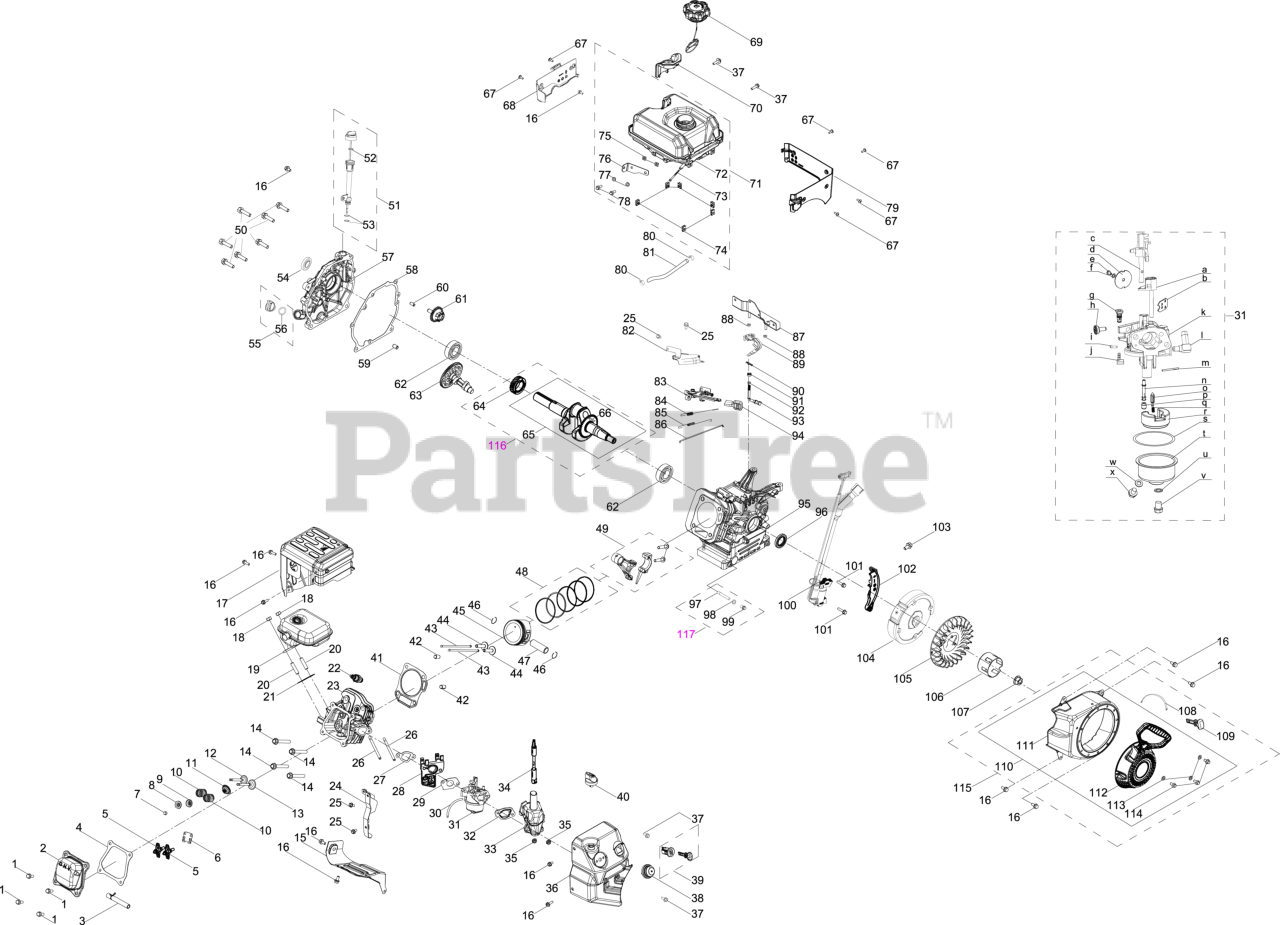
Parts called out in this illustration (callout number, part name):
1	BOLT M6 x 16
2	VALVE COVER
3	BREATHER HOSE
4	VALVE COVER GASKET
5	ROCKER ARM KIT
6	ROCKER ARM BASE
7	EXHAUST VALVE ADJUSTER
8	EXHAUST VALVE SPRING RETAINER
9	INTAKE VALVE SPRING RETAINER
10	VALVE SPRING
11	INTAKE VALVE SEAL
12	EXHAUST VALVE
13	INTAKE VALVE
14	BOLT M8-1.25 x 55 GR10.9
15	AIR SHIELD
16	BOLT M6-1 x 12 GR8.8
17	MUFFLER GUARD
20	STUD M8 x 36
21	MUFFLER GASKET
22	SPARK PLUG (F6RTC/RN11YC/BPR6ES)
23	CYLINDER HEAD
24	SNOW GUARD
25	BOLT M6-1 x 12 GR8.8
26	STUD M6 x 90
27	CARBURETOR INSULATOR GASKET
29	CARBURETOR GASKET
30	PRIMER HOSE
31	CARBURETOR ASSEMBLY
32	CARBURETOR GASKET PLATE
33	HEATER BOX
34	CHOKE LEVER
36	CONTROL PANEL
37	BOLT M6-1 x 18 GR8.8
39	ENGINE KEY SWITCH ASSEMBLY
40	CHOKE LEVER
41	CYLINDER HEAD GASKET
43	PUSH ROD
46	PISTON PIN SNAP RING
47	PISTON PIN
48	PISTON RING SET
49	CONNECTING ROD
50	BOLT M8-1.25 x 32 GR5.8
51	DIPSTICK ASSEMBLY
52	DIPSTICK O-RING
53	OIL FILL TUBE O-RING
56	O-RING 15.8 x 2.5
57	CRANKCASE COVER
58	CRANKCASE GASKET
59	DOWEL PIN 9 X 14
60	DOWEL PIN 9 X 14
61	GOVERNOR GEAR
64	DRIVE TIMING GEAR
65	CRANKSHAFT
66	WOODRUFF KEY
67	BOLT: M5 x 14
68	FUEL TANK SHROUD (RH)
70	DECORATIVE COVER
72	FUEL TANK
73	FUEL FILTER
74	FUEL TANK MOUNT THREADED TAB
76	FUEL TANK MOUNT TAB
77	WASHER 6.5 x 1.5 x 12
78	BOLT M6 x 20
79	FUEL TANK SHROUD (LH)
80	HOSE CLAMP
81	FUEL HOSE 6.3 x 12.5 x 162
82	GOVERNOR SHIELD
83	GOVERNOR GEAR BRACKET ASSEMBLY
84	GOVERNOR SPRING
85	THROTTLE SPRING
86	THROTTLE LINKAGE
87	FUEL TANK BRACKET
89	GOVERNOR LEVER
90	COTTER PIN
91	GOVERNOR SEAL
93	GOVERNOR SHAFT
94	THROTTLE CONTROL KNOB
96	OIL SEAL
97	OIL DRAIN PIPE
98	WASHER
99	OIL DRAIN PLUG
100	IGNITION MODULE
101	BOLT M6-1 x 25 GR8.8
102	LOWER SHIELD
103	SCREW M6-1 x 20 CL5.8
105	COOLING FAN
106	STARTER CUP
107	FLYWHEEL NUT
108	CABLE TIE - 3 x 150
109	IGNITION KEY
110	RECOIL STARTER
111	BLOWER HOUSING
112	RECOIL STARTER ASSEMBLY
113	RECOIL FLAT WASHER
114	BOLT M6 x 10
115	RECOIL STARTER
116	CRANKSHAFT
117	Oil Drain Pipe
